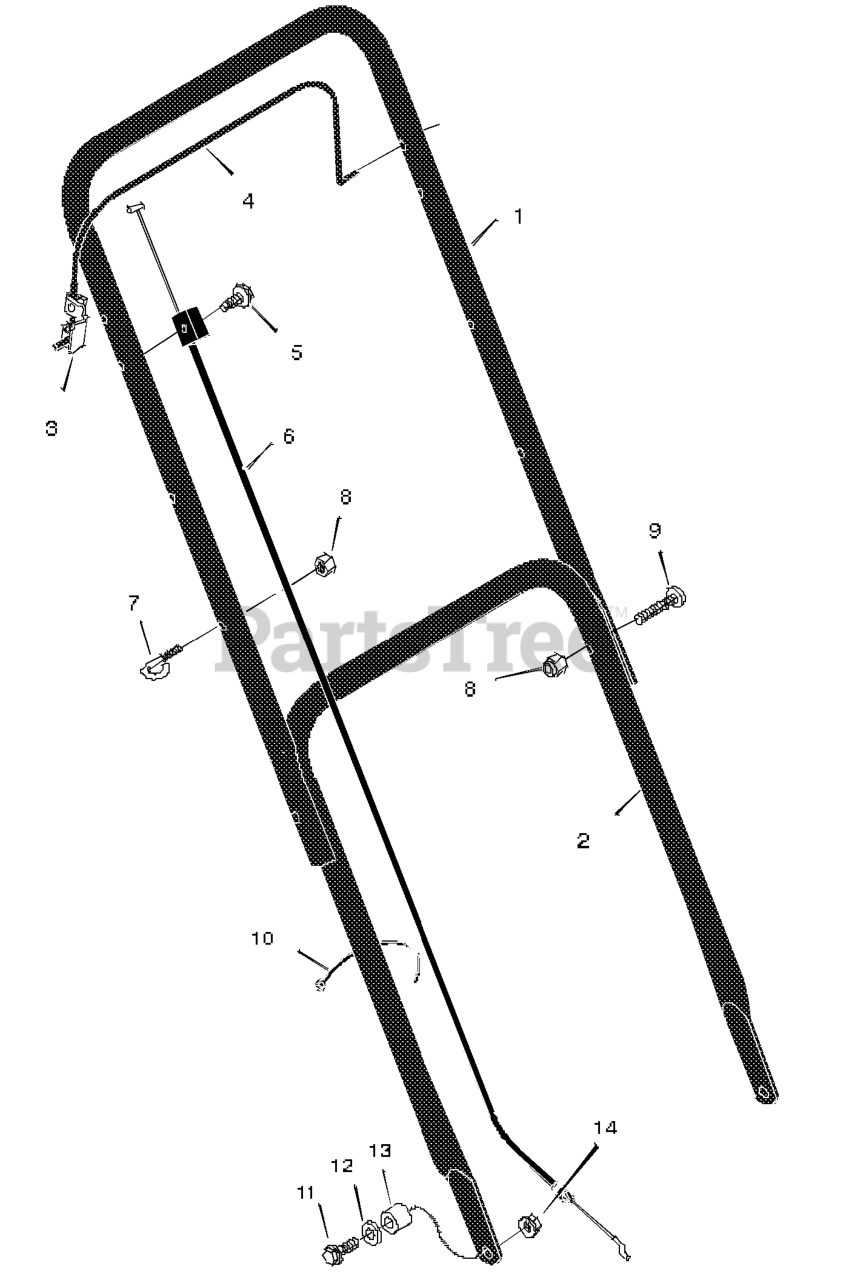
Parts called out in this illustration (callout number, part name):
1	Handle, Upper (Black)
2	Handle, Lower (Black)
3	Bracket, Stop Lever
4	Lever, Stop
6	Engine Stop Cable
7	GUIDE, ROPE
8	Locknut
10	Fastener, Cable
11	Bolt
14	Nut
